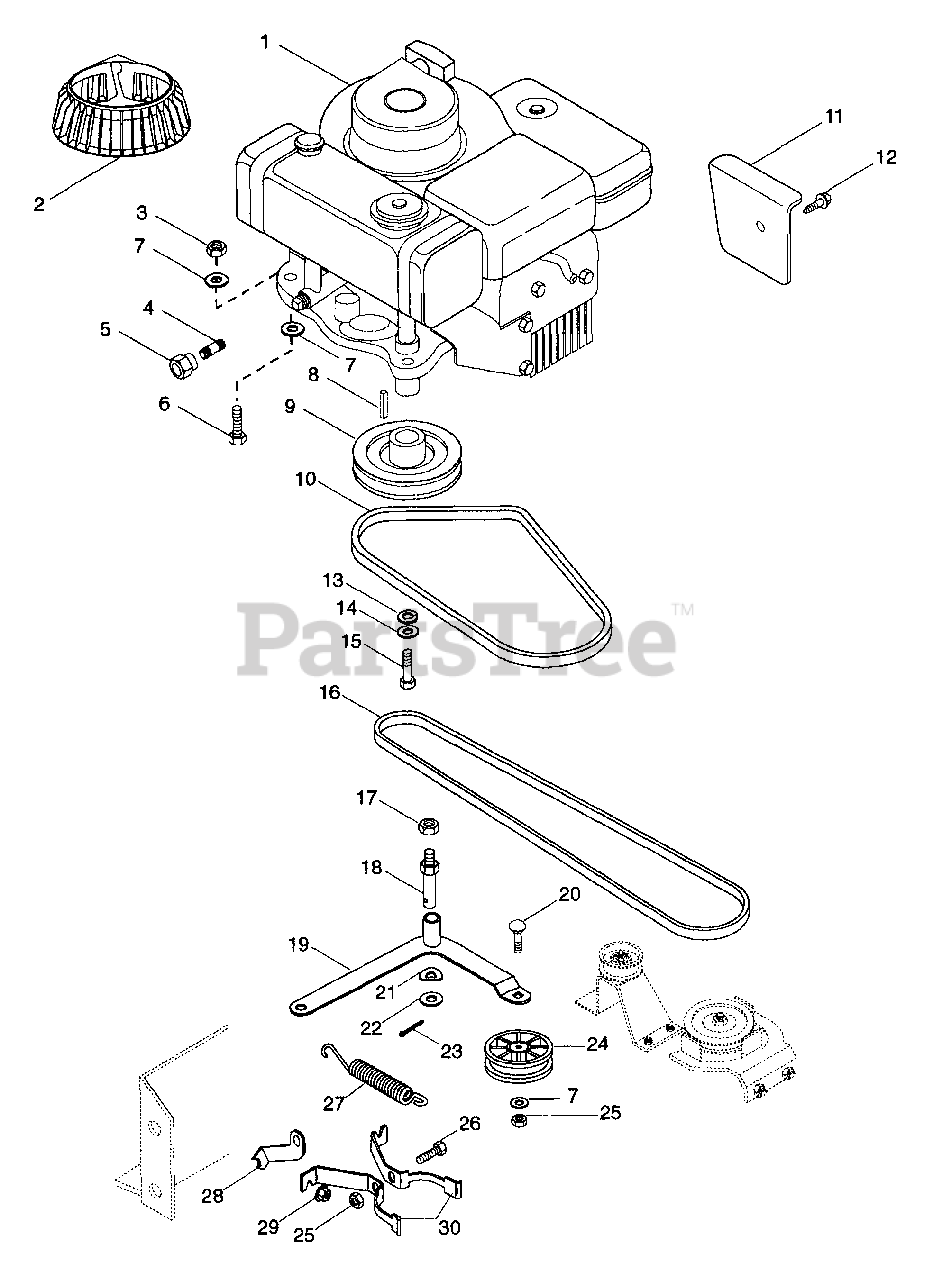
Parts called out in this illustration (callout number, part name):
1	ENGINE- 8HP B&S
2	PRE-GUARD- REWIND (B&S#280685)
3	NUT-LK-TOP .312-18 GR C PL
5	PIPE CAP
6	BLT-HEX .31-18X1.50 PL GR5
7	WSHR-FL-STL .328X.875X.062 PL
8	KEY-STR .25X2.0X.25
9	ENGINE SHEAVE
10	V-BELT, 3L-RAW EDGE
11	GUARD
12	SCR-TAP 10-24X.375 HWH PL TR
13	WSHR-FL-STL .505X1.140X.250
14	WSHR-LK .438X.133 HVY
15	BLT-HEX .44-20X1.25 GR5
16	V-BELT, HA-RAW EDGE
17	NUT-LK-CTR .375-16 GR A PL
18	SHOULDER STUD
19	IDLER ARM
20	BLT-RDHDSQNK .31-18X1.25 SHTPL
21	WAVE WASHER .531X.781X.125FH
22	WSHR-FL-STL .505X.875X.024 PL
23	PIN-COTR .09X.75 PL
24	IDLER-FLAT 2.75X.31 DAYCO
25	NUT-LK .312-18 GR A PL
26	BLT-HEX .31-18X.75 PL GR2
27	SG-TENS .062X.72X6.65 WLD 7
28	BELT FINGER BRACE
29	NUT-FLG. .312-18 PL
30	BELT FINGER
